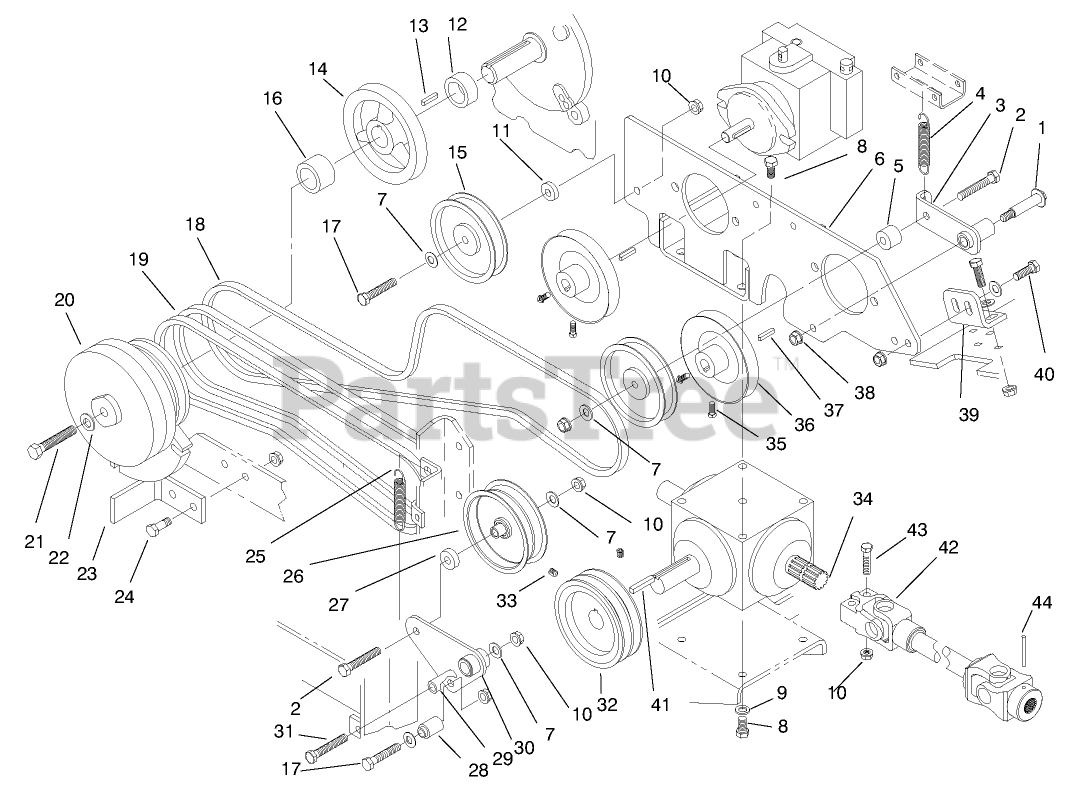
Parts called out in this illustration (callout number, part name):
1	BOLT-WHEEL
2	SCREW-HH
3	IDLER ARM ASM
4	SPRING-EXTENSION
5	SPACER-ARM, IDLER
6	PUMP MOUNT ASM
7	WASHER-FLAT
8	SCREW-HHF
10	NUT-LOCK, NI
11	Washer
12	SPACER-SHAFT, ENGINE
14	PULLEY-ENGINE
15	PULLEY-IDLER
16	SPACER-SHAFT, ENGINE
17	SCREW-HH
18	V-BELT
19	BELT - PTO (SET)
20	Clutch ASM
21	SCREW-HH
22	WASHER-FLAT
23	STOP-CLUTCH
24	SCREW-HH
25	SPRING-EXTENSION
26	PULLEY-IDLER
27	SPACER-IDLER
28	SPACER - SPRING
29	SPACER
30	IDLER ARM ASM
31	Screw-Hhcs
32	PULLEY-CLUTCH
33	SCREW-HSH
34	Gearbox-PTO Drive
35	SCREW-SET
36	PULLEY-PUMP, TRACTION
37	KEY-PUMP
38	NUT-LOCK
39	MOUNT-PLATE, PUMP
40	SCREW-HHF
41	KEY-SQUARE
42	SHAFT-DRIVE
43	SCREW-HH
44	PIN-SPRING
